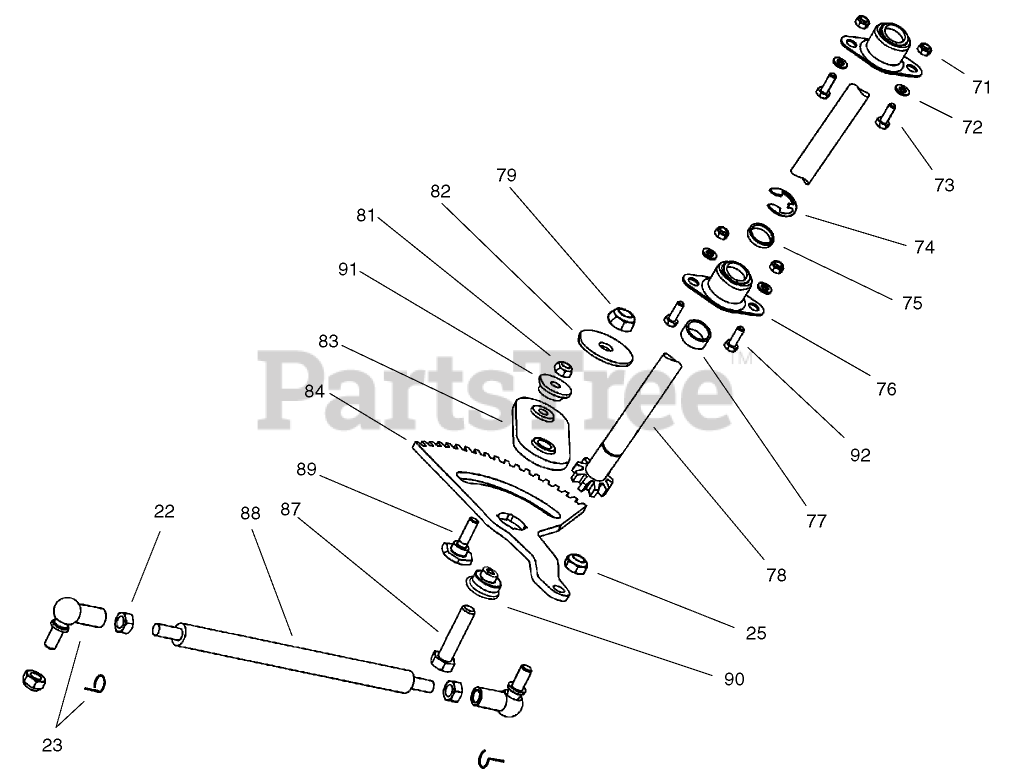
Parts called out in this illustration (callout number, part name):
25	NUT-SELF LOCKING
71	NUT-LOCK, NI
72	WASHER-PLAIN
73	SCREW-HH
74	CLIP-SPRING
75	SPACER-UPPER
76	BEARING-SPHERICAL
77	SPACER-LOWER
78	GEAR-STRG SHAFT PINION
79	NUT-HEX
81	NUT-LOCK, NI
82	WASHER-PLAIN
83	Plate-Steering
84	GEAR-SECTOR
87	SCREW-HH
88	LINK-DRAG
89	Bolt-Shoulder
90	Pivot-Steering
91	Bushing
92	SCREW-HH
